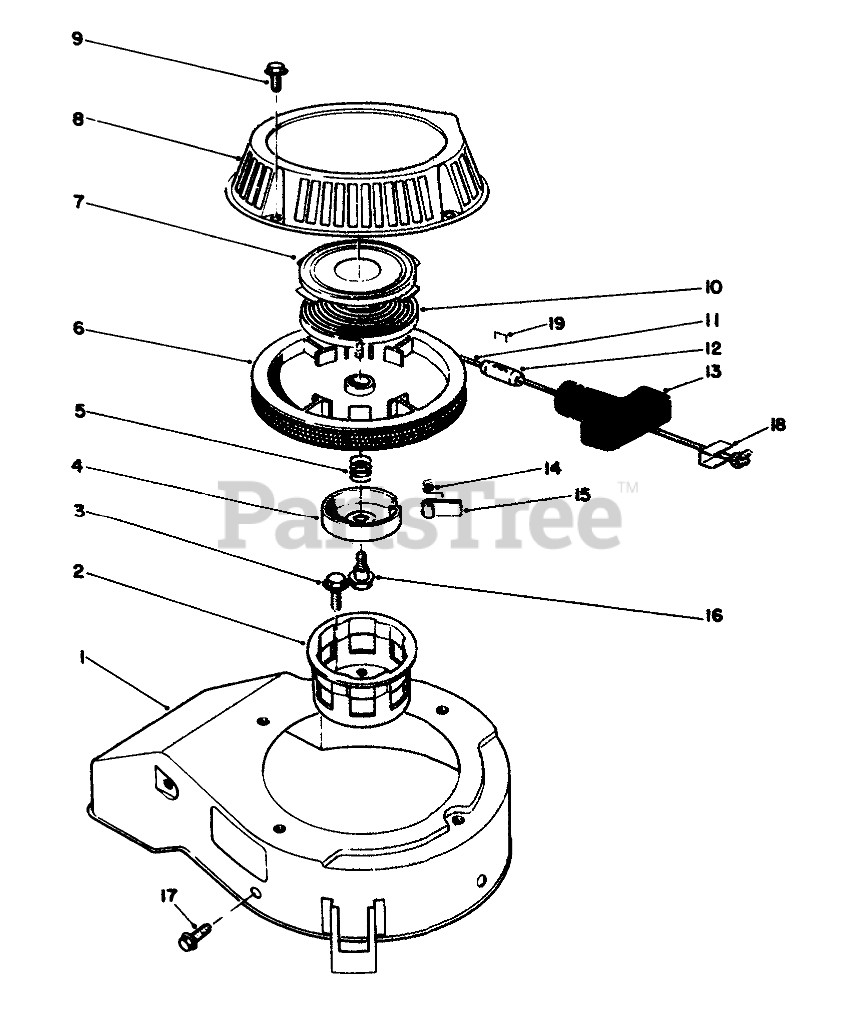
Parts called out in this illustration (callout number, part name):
1	COVER
2	CUP - STARTER
4	RETAINER
5	SPRING
7	Retainer Cup-Recoil Spring
9	SCREW-HHF
10	Spring-Recoil
11	ROPE-STARTER
13	HANDLE-RECOIL
14	SPRING
18	Insert Handle
19	Staple
